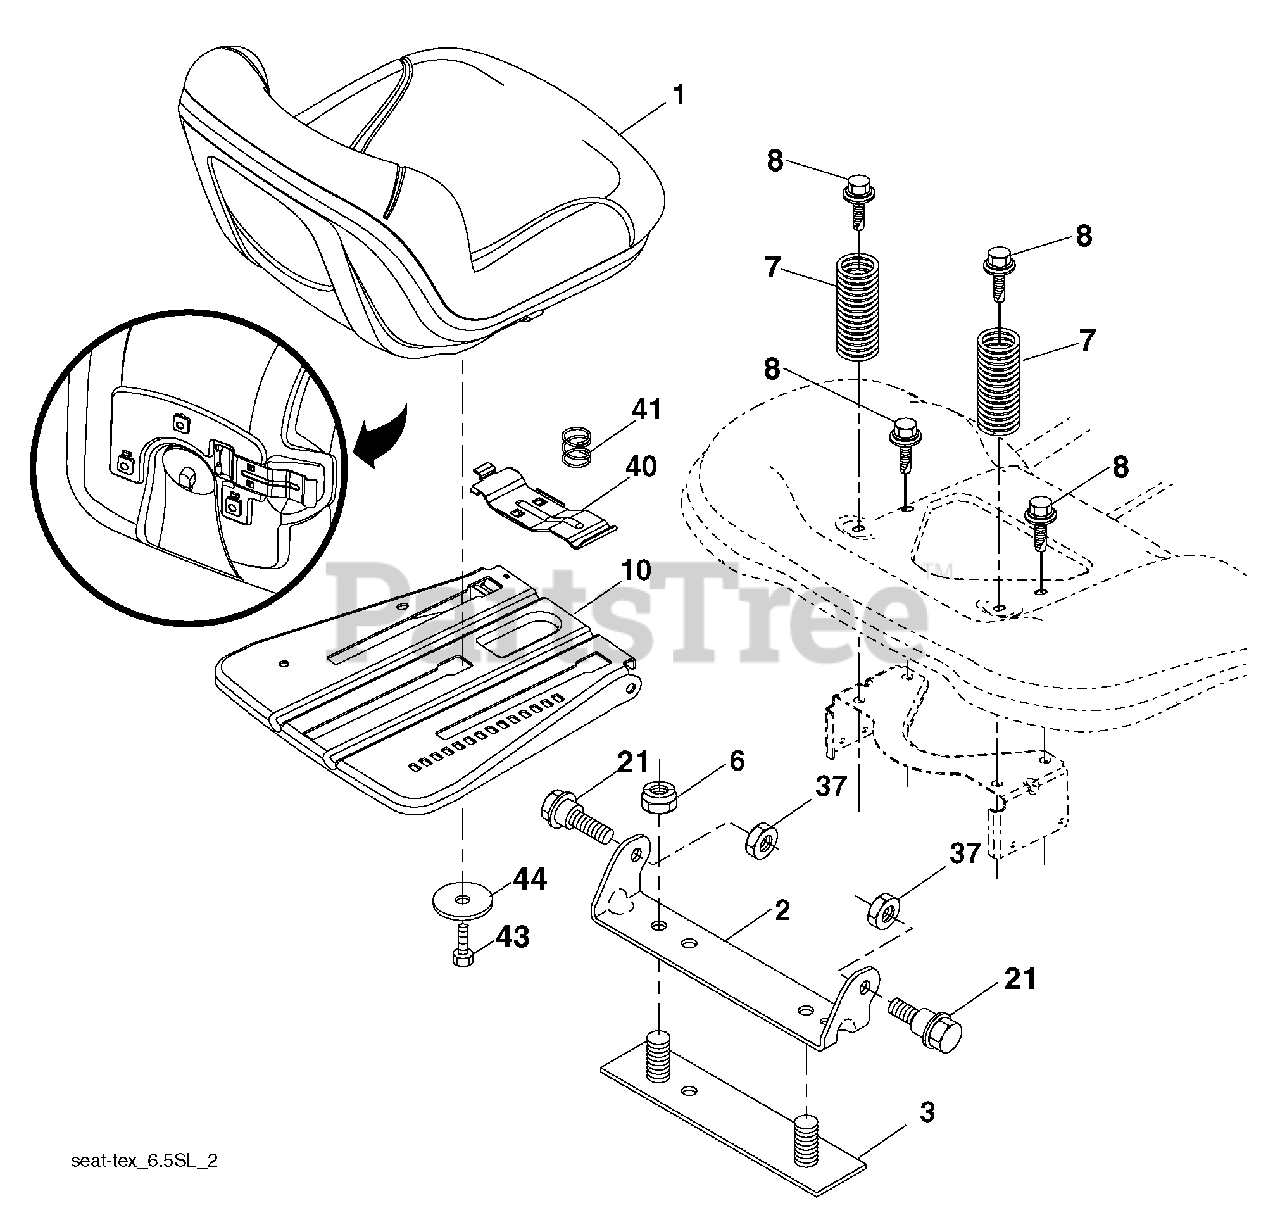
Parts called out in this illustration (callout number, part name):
1	Seat
2	Bracket Pivot Fender
3	Strap, Asm Fender
6	Nut, Lock W/Ins. 3/8-16 unc
7	Spring, Seat Cprsn
8	Bolt 5/16-18 uncx 3/4 w/Sems
10	Pan, Seat
21	Bolt, Shoulder 5/16-18
37	Nut, Lock 5/16-18 unc
40	Handle Slide Seat
41	Spring Latch Seat
43	Bolt Fin Hex 3/8-16 UNC x 3/4
44	Washer 13/32 x 2-3/8 x 12Ga.
